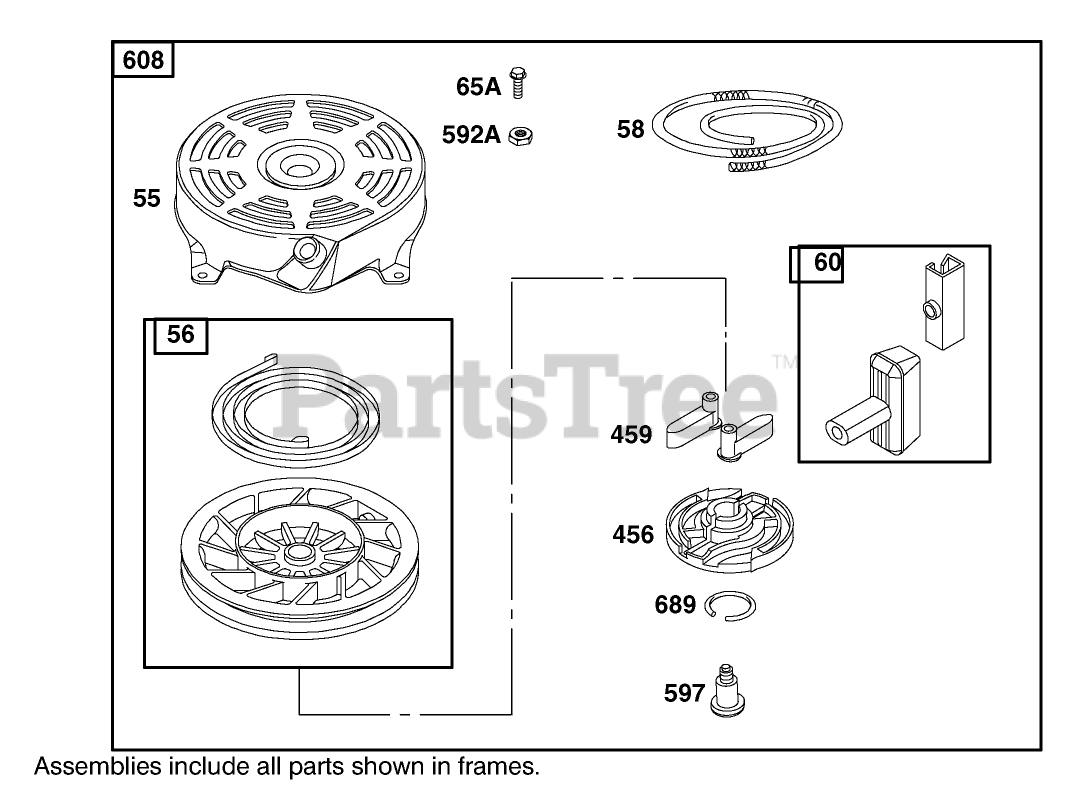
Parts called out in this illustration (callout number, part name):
56	PULLEY-STARTER, REWIND
58	ROPE-STARTER
65A	SCREW-HH
456	RETAINER-STARTER, REWIND
459	PAWL-STARTER
592A	NUT-HEX
608	REWIND ASM
689	SPRING-TORSION
